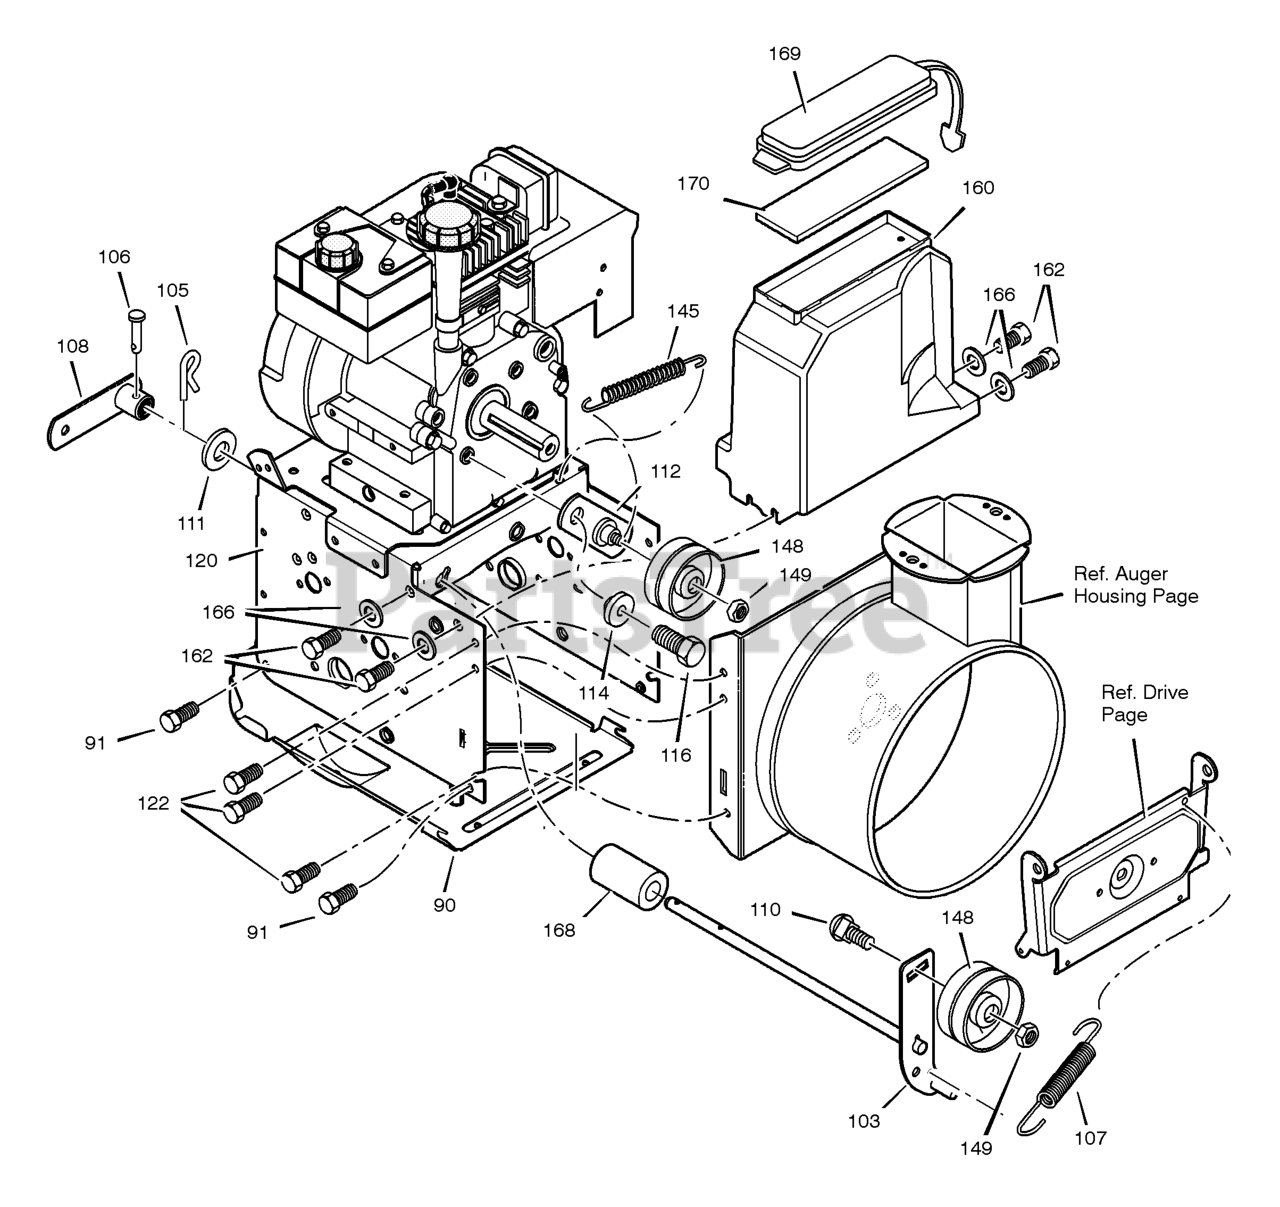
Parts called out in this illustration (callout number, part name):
90	COVER, BOTTOM
91	SCREW, 1/4-20X .63
103	IDLER ASSEMBLY, AUGER
105	PIN, HAIR .38DIAX1.64LG
106	PIN, KLIK 3/16" DIA
107	SPRING, TENSION
108	ASSY., SPRING ATTACH
110	BOLT, 3/8-16X1.25 CARR.
111	WASHER, FLAT
112	BRACKET ASSEMBLY, IDLER
114	BUSHING, IDLER BRACKET
116	SCREW 5/16-24 X .75
118	WASHER, SPLIT
122	SCREW, TAP 5/16-18 X .50
145	SPRING, IDLER TRACTION DRIVE
148	PULLEY, IDLER
149	NUT, JAM 3/8-16
160	COVER, BELT -GRAY
162	SCREW, Hex Head
166	WASHER, FLAT
168	SPACER, AUGER BRACKET
169	LID, TOOL BOX
170	PAD, FOAM
